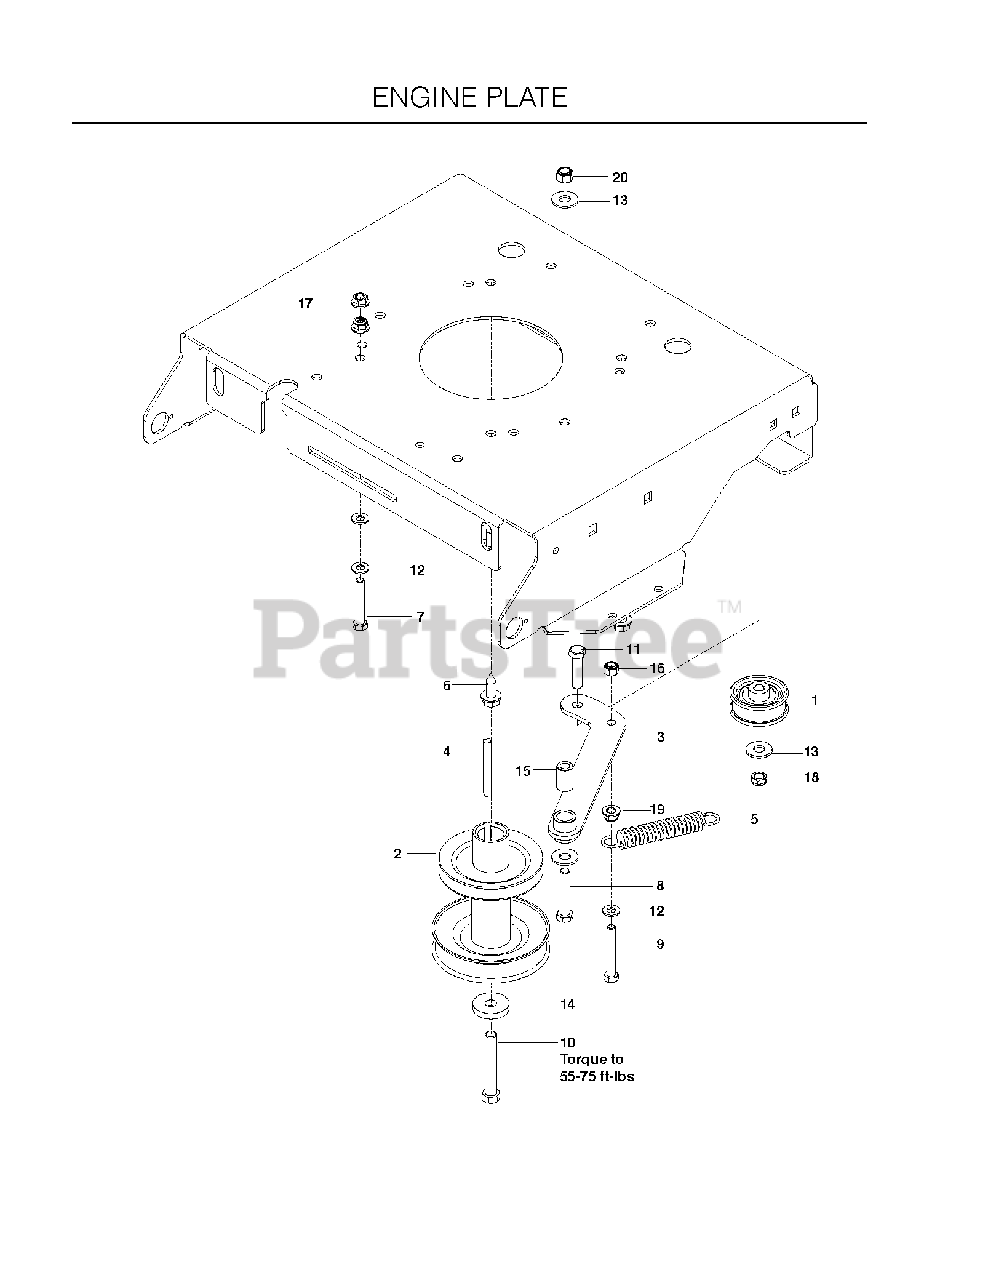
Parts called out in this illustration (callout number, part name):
1	PULLEY IDLER
2	PULLEY, ENGINE 30"
3	IDLER WLDT.
4	KEY 1/4 SQ X 2-1/2
5	SPRING - 3.50
6	HHFS 3/8-16 X 1.0 THD FORMING
7	HCS 5/16-18X2
8	HCS 3/8C X 2
9	CAPSCREW
10	HCS 7/16-20 X 2-3/4
11	HCS 3/8C X 1 1/2
12	FLAT WASHER 5/16 SAE
13	WASHER 3/8 FLAT
14	WASHER .43X1.38X.25
15	BUSHING
16	NUT 5/16 NYLOC
17	NUT 5/16C WHIZ
18	NUT HEX 3/8-16 NYLON, THIN
19	5/16-18 NYLOC FLANGE NUT
20	NUT 3/8-16 NYLOC
